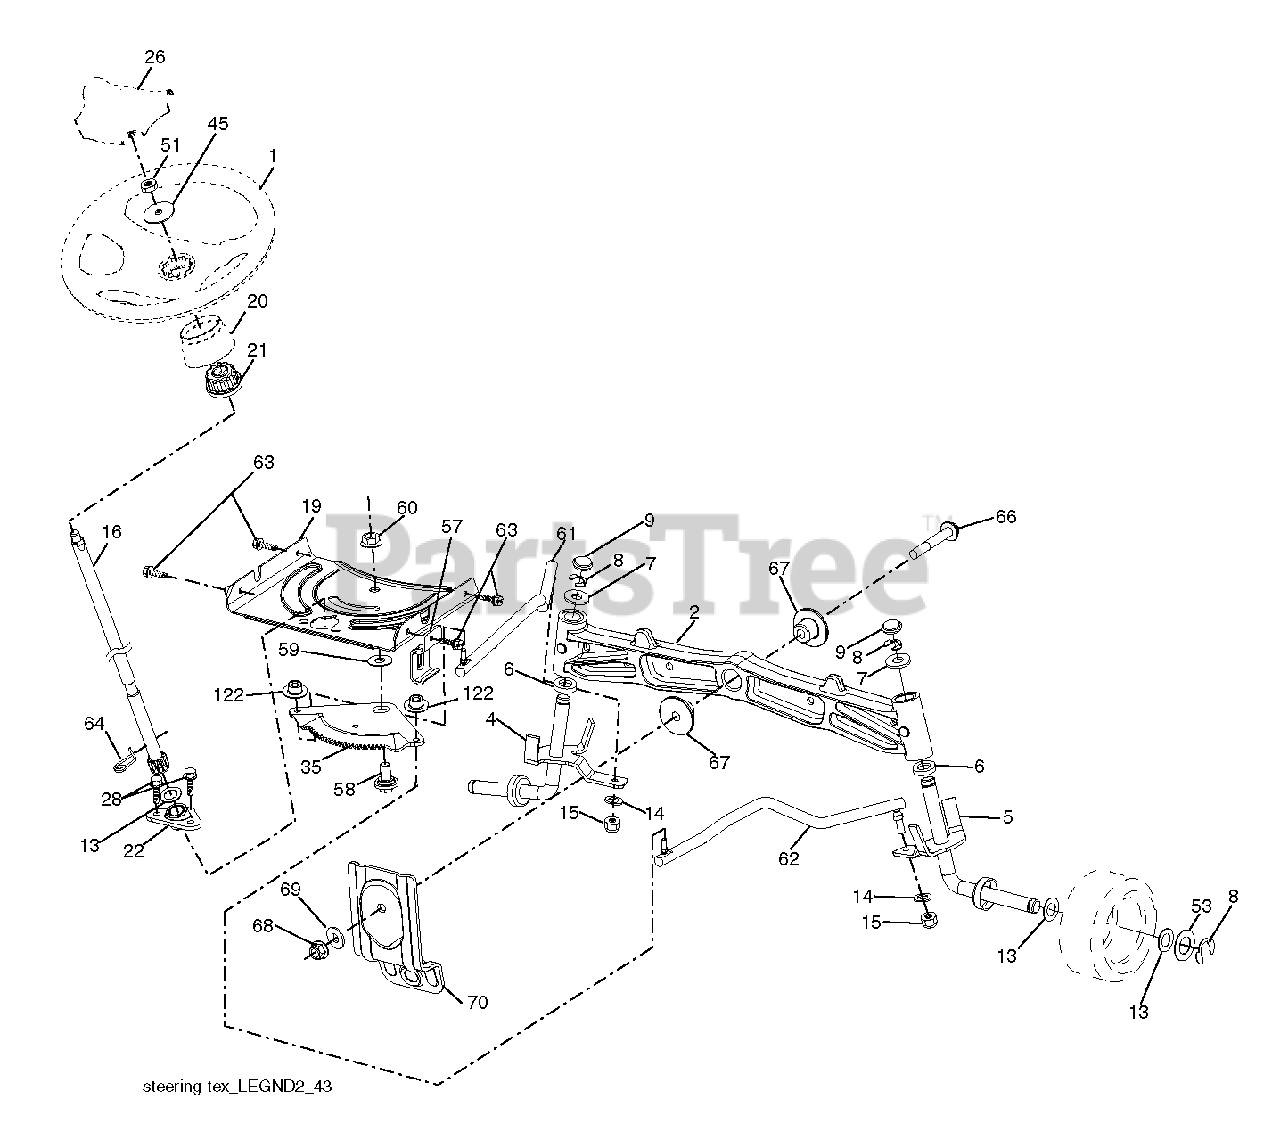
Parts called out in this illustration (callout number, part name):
1	WHEEL, STEERING
4	SPINDLE ASSY LH
5	SPINDLE.WELDED.RH.16"TEX
6	BRNG T
14	WASHER, LOCK 3/8
15	NUT CROWNLOCK 3/8-24
19	PLATE.STEER.DDL.NLT/NG
20	BOOT.STEERING.
21	ADAPTER, WHEEL STNG
22	STEERING.SUPT.LOWER.
26	INSERT, WHEEL STEERING
28	SCREW, 3/8-16X3/4
35	GEAR.SECTOR.PLATE.DDL.
57	BRKT.UPSTOP.GT/LT.TEX
58	BOLT.SHOULDER.SECTOR.P
59	WASHER.THURST.SECTOR.S
60	NUT FLANGE LOCK 5/8-11
61	DRAGLINK.LH.BALLSTUD.D
62	DRAGLINK.RH.BALLSTUD.D
63	SCREW
64	RETAINER.CLIP.SPRING.S
66	BOLT HEX FGHD 7/16-14 X 3 SERR
67	BUSHING.PM.FRONT AXLE
68	NUT.LOCK.FLANGE.7/16
69	WASHER.1.5X.505X.118
70	BRKT.DECK.SUSPENSION.F
